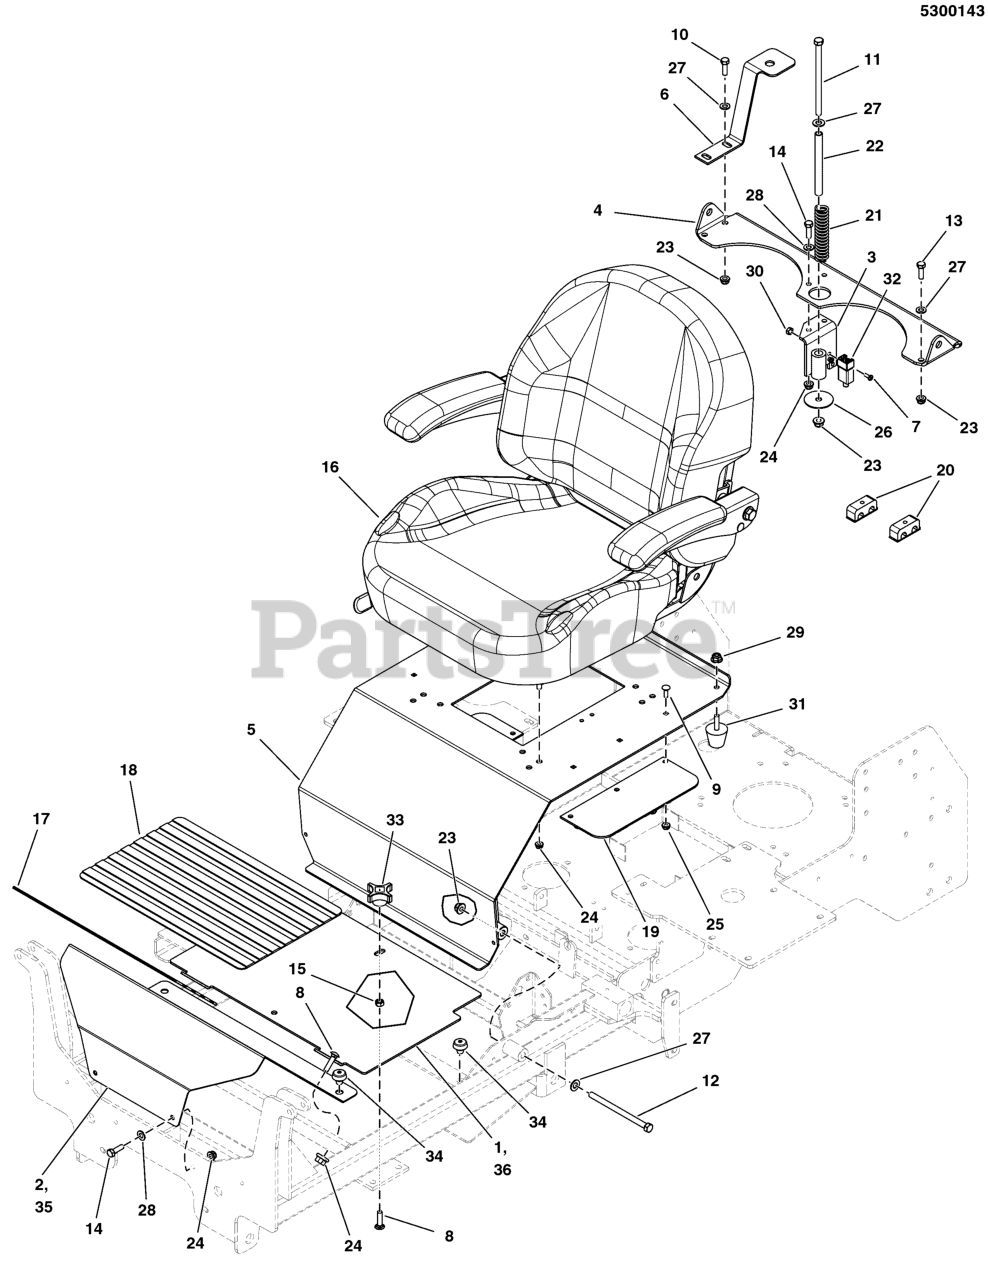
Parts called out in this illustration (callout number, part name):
1	PLATE, FLOOR REMOVABLE, IS2000Z - RED
2	PLATE, FRONT FLOOR, IS2000Z - RED
3	WELD, BRACKET, SPRING SWITCH - RED
4	PLATE,SEAT SUPPORT - RED
5	WELD, SEAT PLATE - IS2000 - RED
6	BRACKET, FUEL VALVE, IS2000 - BLK
7	SCREW, #10-24 X 3/4 ROUND PHILLIPS
8	BOLT, 5/16-18 X 1-1/4, CARRIAGE YZ
9	BOLT,1/4-20X0.750,GR5,STD NECK,SQ,ZC/CL
10	BOLT, 3/8-16 X 1" GD5 CZ
11	BOLT, 3/8-16 X 6" GD5 CZ
12	BOLT, 3/8-16 X 5-1/2" GD5 CZ
13	BOLT, 3/8-16 X 1-1/4" GD5 CZ
14	BOLT, 5/16-18 X 1 GD5 YZ
15	NUT, 5/16-18, GRB, HEX, CNTR LK, ZINC/CL
16	SEAT, 2012
17	SAFETY WALK, FLOOR REST, 6.00 X 16.00
18	SAFETY WALK, FLOOR PLATE, S50X, 10X16
19	PLATE, SEAT, RUBBER FLAP
20	CLAMP, 1/2" HOSE, DOUBLE, PLASTIC
21	SPRING, .688 ID X .130 WIRE DIA 4.25
22	SPACER, .38 X .50 X 5.06
23	NUT, 3/8-16 HEX NYLOCK FLANGE
24	NUT, 5/16-18 HEX NYLOCK FLANGE
25	NUT, 1/4-20 HEX NYLOCK FLANGE
26	WASHER, .39 X 2.00 X X .14
27	WASHER, 3/8 SAE
28	WASHER, 5/16" SAE
29	NUT, 5/16-18 HEX SERRATED FLANGE (SMALL)
30	NUT, #10-24 HEX
31	BUMPER, RUBBER 5/16-18
32	SWITCH, PLUNGER, N.C./N.C.
33	KNOB-INT THR .312-18 4-ARM 2.12WD 1.06LG
34	MNT, VBRTN, RBBR
35	PLATE, FRONT FLOOR, IS2000Z - RED
36	PLATE, FLOOR REMOVABLE, IS2000Z - RED
